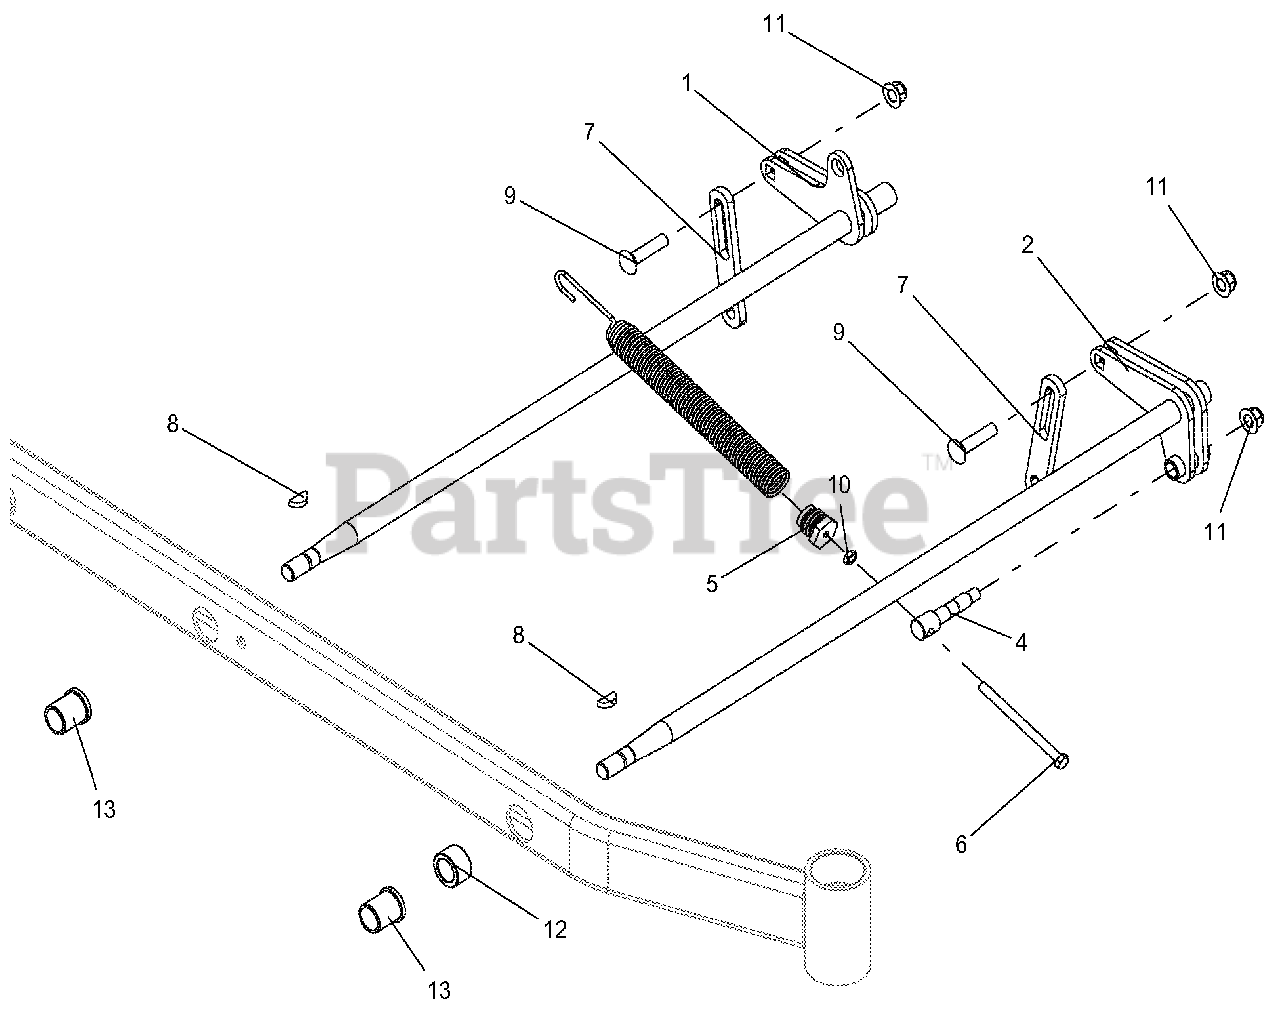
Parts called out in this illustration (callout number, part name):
1	WLDMT, REAR LH DECK LIFT ARM-BLACK
2	WLDMT, FRONT LH DECK LIFT ARM-BLACK
4	TRUNION, SPRG
5	PLUG, SPRG
6	BLT-HEX .38-16X5.00 GR5 YWZC
7	LINK, DECK LIFT - LONG
8	KEY, WDRF .25 X 1.00 HRD #15
9	BLT-RDHDSQNK .50-13X2.25 G5 Y
10	NUT, JAM .375-16 YWZC
11	NUT-LK-NYL-FLG .50-13 YWZC
12	SPACER, 1.500 X 1.000 X .880
13	BSHG-FLG 1.00X1.25X1.5X1.5
